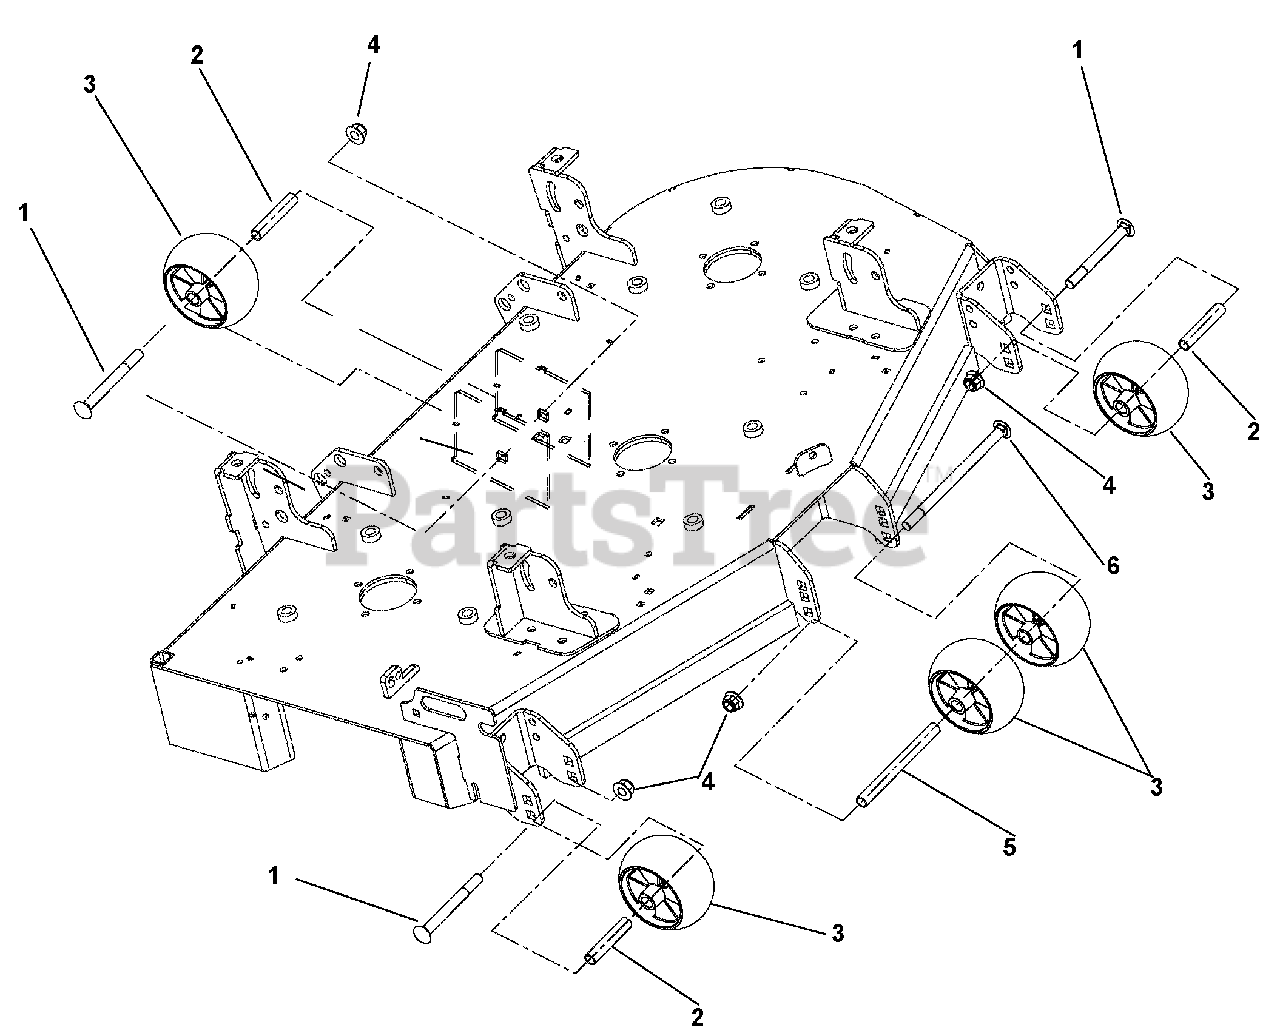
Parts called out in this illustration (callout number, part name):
1	Bolt, Round Head Square Neck .50-13 x 5.00 (991300)
2	Spacer, .510 x .625 x 3.35 (991300)
3	Anti-Scalp Wheel (991300)
4	Nut, .50-13 Nyloc Flange (991300)
6	Bolt, Round Head Square Neck .50-13 x 8.50
